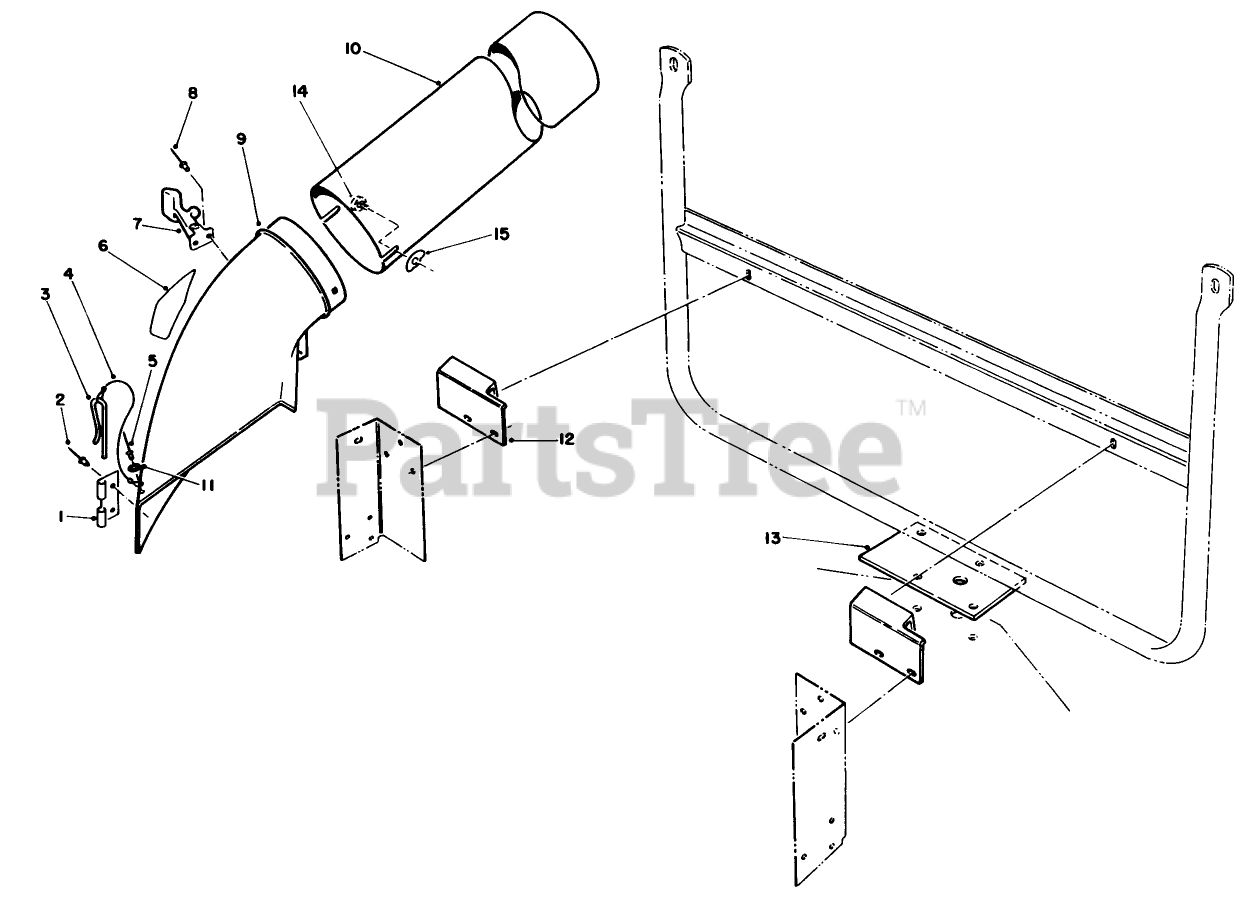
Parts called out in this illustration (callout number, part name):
1	BRACKET-MOUNTING, CHUTE
2	RIVET-BLIND
3	PIN-LOCKING, CHUTE
4	LANYARD
5	RIVET-BLIND
8	RIVET-POP
9	CHUTE ASM
11	WASHER-PLAIN
14	BOLT-CARR
15	NUT-WING SPECL
